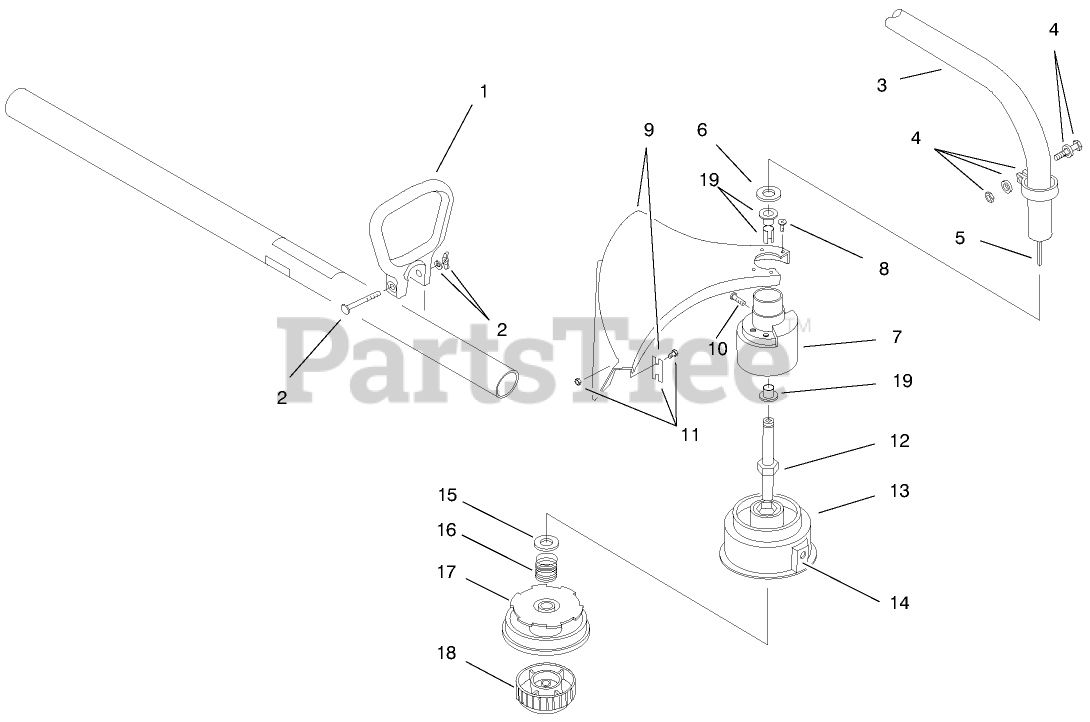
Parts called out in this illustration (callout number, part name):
2	HARDWARE - D-HANDLE
4	CLAMP ASM - UPPER
5	SHAFT - FLEXIBLE DRIVE
7	BUSHING HSG ASM
8	GUARD MTG SCREW ASM
10	ANTI-ROTATION SCREW
11	BLADE ASM
13	OUTER SPOOL EYELET ASM
14	EYELET
15	RETAINER WASHER
16	SPRING
17	REEL - INNER
18	KNOB ASSEMBLY-SMALL BUMP
19	Bushing Housing Asm. (Not Serviced Separately)
